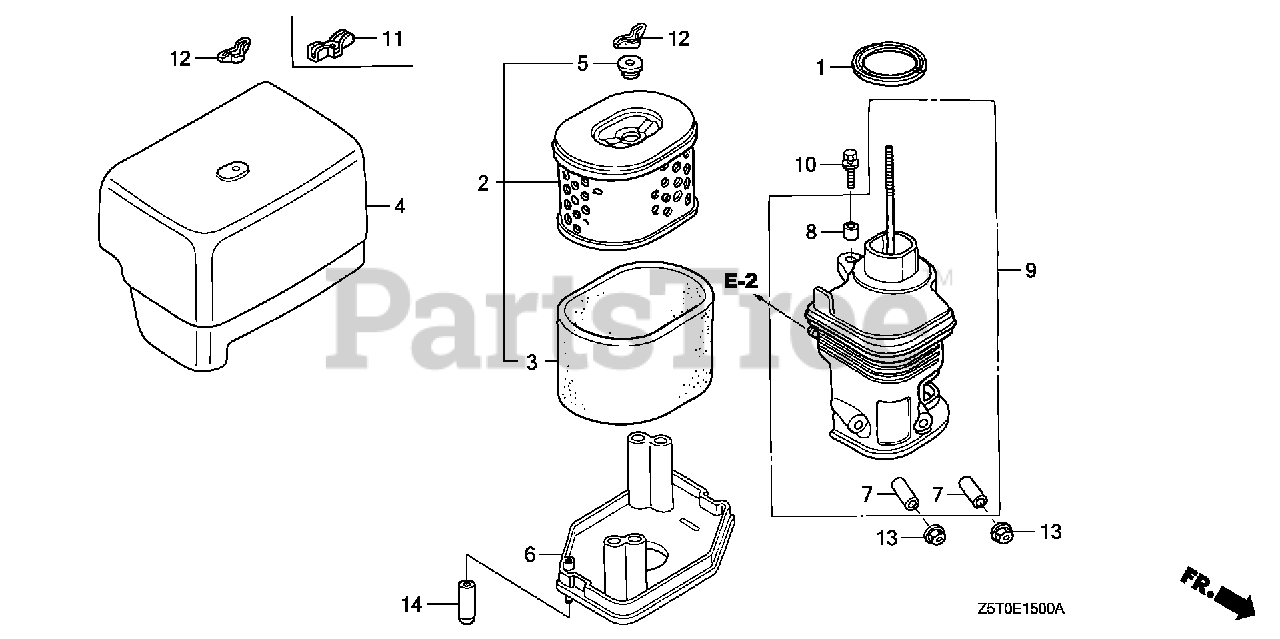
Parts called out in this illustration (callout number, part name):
1	GASKET, ELBOW
2	ELEMENT, AIR CLEANER
3	FILTER (OUTER)
4	COVER, AIR CLEANER
5	GROMMET, AIR CLEANER
6	NOSE, MUFFLER
7	COLLAR, AIR CLEANER
8	COLLAR B, AIR CLEANER
9	ELBOW, AIR CLEANER
10	BOLT-WASHER (6X22)
12	WINGNUT, TOOL BOX SETTING
13	NUT, FLANGE (6MM)
14	CAP, SEALING
